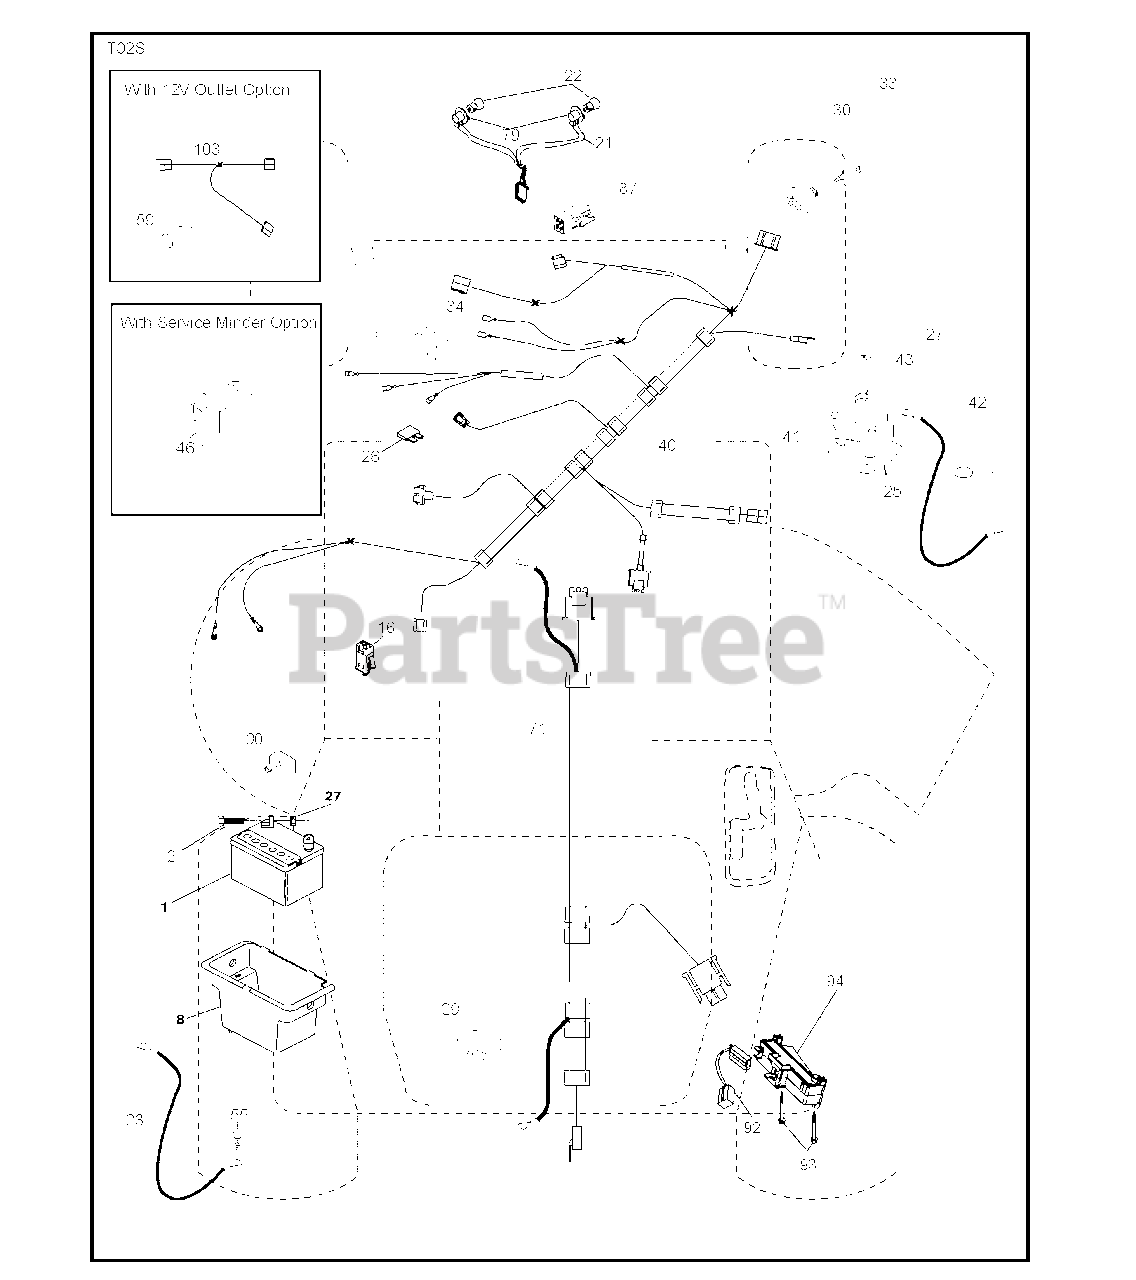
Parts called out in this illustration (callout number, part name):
1	REPL BY 532 12 38-99
8	BOX.BATTERY.MNT.REAR.L
16	SWITCH INTERLOOK PUSH-IN
21	HARNESS.LIGHT W/4152J BULBS
22	LIGHTBULB
25	CABLE.STARTER.6GA.BL/RED.14.
26	FUSE 20AMP
27	NUT
28	CABLE.BLACK.18"REAR.BA
29	SWITCH.SEAT.DELTA.OPC.
30	SWITCH.IGN.DELTA.W.LGH.ROS
33	KEY.CHAIN.BLISTER.PACK.GEN.INT
34	SWITCH LT
40	HARNESS IGN. DASH
41	SCREW
42	TERMINAL COVER
43	SOLENOID.W/BRASS.PLUNG
55	SCREW 5/16"
71	HARNESS.IGN.CHASS.TEX.REAR.BAT
79	BULB HOLDER ASM.
87	SWITCH.INTRLCK.CLUTCH.
90	COVER, TERMINAL BATTERY
92	HARNESS.PIGTAIL.CONSLE
93	SCREW.PLASTITE
94	MODULE.REVERSE.ROS
